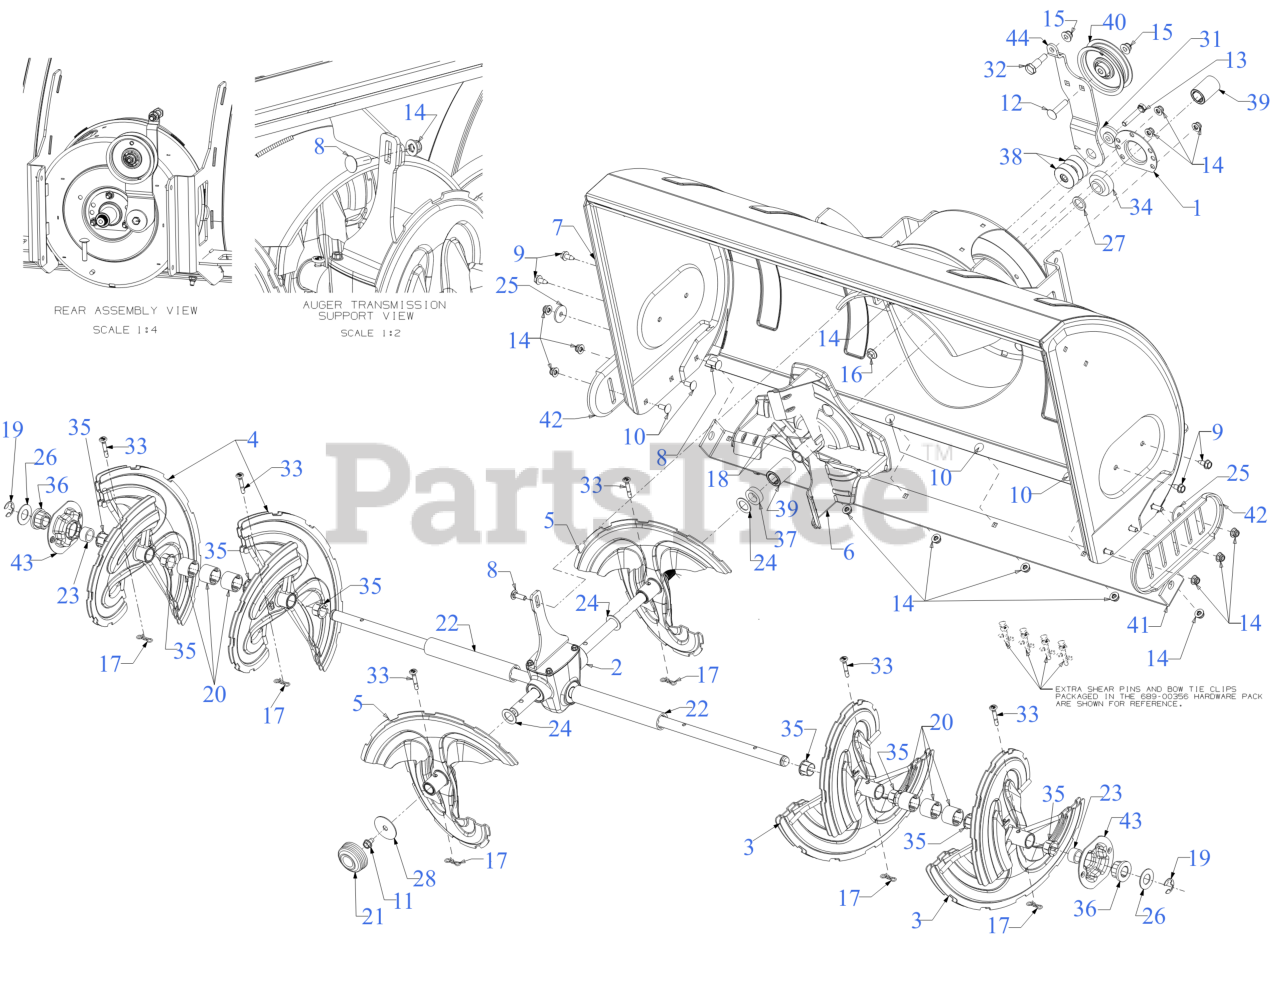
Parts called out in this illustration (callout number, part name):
1	HOUSING-BEARING
2	42" AUGER GEARBOX ASSEMBLY
6	IMPELLER ASSEMBLY (POWDER BLACK)
8	CARRIAGE BOLT 5/16-18 x 1.00
9	SCREW 5/16-18 x .750
10	CARRIAGE BOLT 5/16-18 x .75
11	SCREW 5/16-18 x .500
12	BOLT 3/8-16 x 1.69 GR5
13	SCREW 3/8-16 x 2.0 GR 8
14	FLANGE LOCK NUT 5/16-18
16	FLANGE LOCK NUT
17	BOW TIE COTTER PIN 1/4-5/16
20	SPACER 1.25OD x .75ID X1.00 LG
24	FLAT WASHER .793ID x 1.24OD x .060
25	WASHER-5/16 x 1.25X 1.27
26	FLAT WASHER
27	FLAT WASHER .75 x 1.13 x .10
28	HUB CAP WASHER .406 x 1.92 x .060
31	SHOULDER SPACER
32	SHOULDER BOLT .50X.892X3/8
33	SHEAR PIN (.25 x 1.50)
33	Cub Cadet SHEAR PINS (3X SNOW)
33	Troy-Bilt SHEAR PINS (3X SNOW)
33	KIT-SHEAR PIN 3 STAGE (05273/06654)
34	BEARING W/OUT COLLAR
35	FLANGE BUSHING
36	FLANGE BEARING
38	SPACER .385ID x 1.75OD x .585THK
40	FLAT PULLEY
41	SHAVE PLATE 42"
42	SLIDE SHOE (POWDER BLACK)
44	IDLER PIVOT BRACKET (POWDER BLACK)
